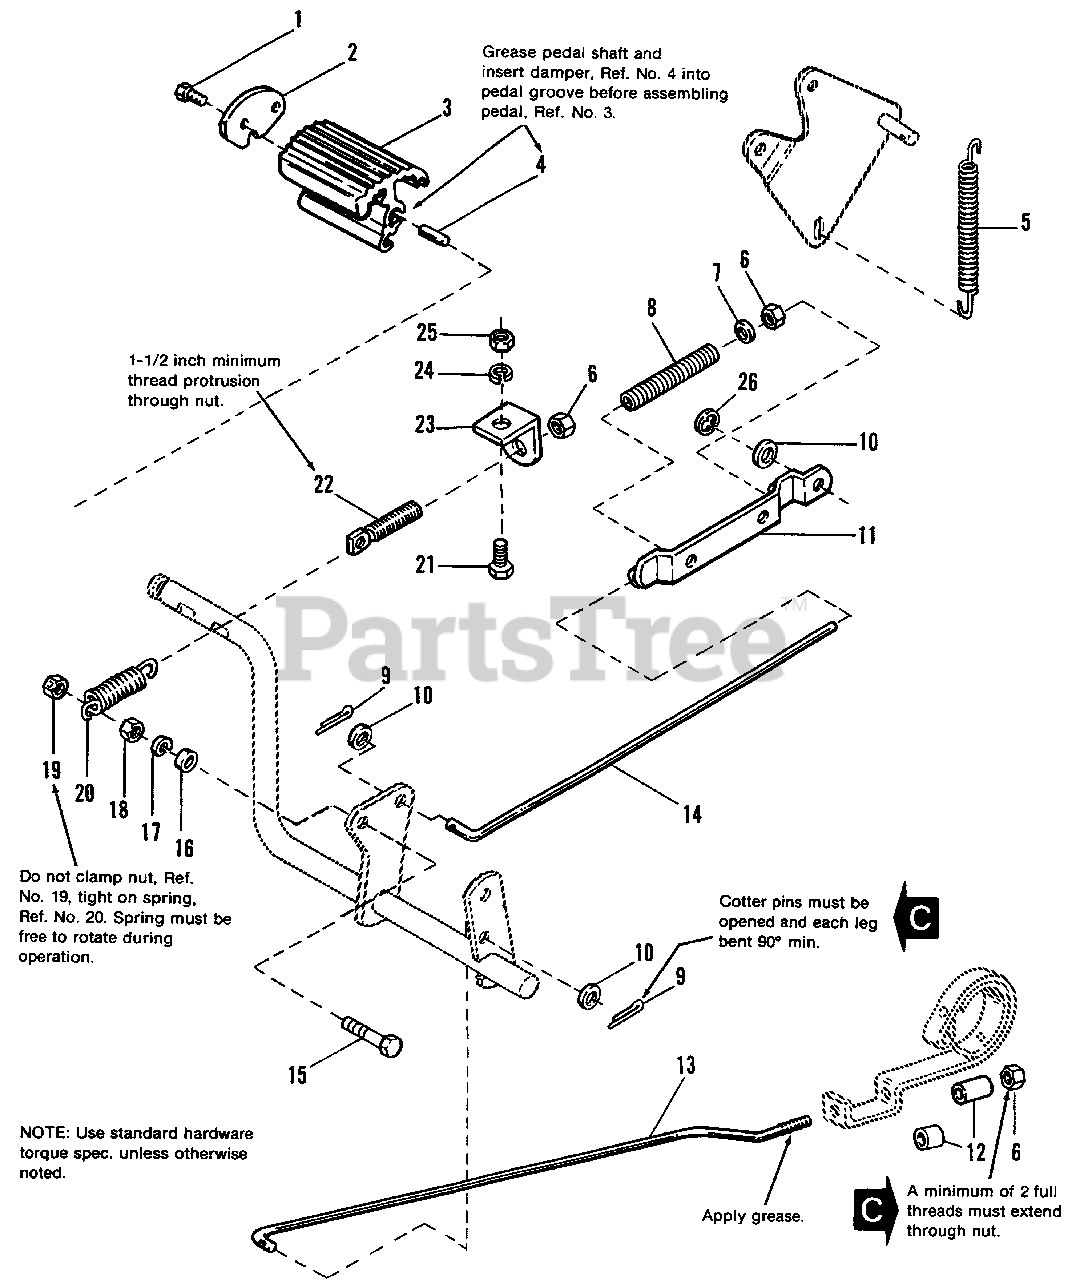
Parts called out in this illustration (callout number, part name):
1	SCREW, Taptite, 1/4-20 x 5/8
2	END PLATE
3	PEDAL, Foot
4	DAMPER, Rubber
5	SPRING, Tension, Idler
6	LOCKNUT, 13/32 I.D. x 1 O.D.
7	WASHER
9	PIN, Cotter, 3/32 x 3/4
10	WASHER, 3/8
11	GUIDE ASSY., Clutch Rod
12	SPACER (Except Mfg. No. 1690927 & 1690930)
12	SPACER (Mfg. No. 1690927 and 1690930)
14	ROD, Clutch (Except Mfg. No. 1690927 and 1690930)
14	ROD, Clutch (Mfg. No. 1690927 and 1690930 only)
15	CAPSCREW, Hex, 3/8-16 x 1-3/4
17	LOCKWASHER, 3/8
18	NUT, Hex, 3/8-16
19	LOCKNUT, Hex, 3/8-16
20	SPRING, Tension
21	CAPSCREW, Hex, 5/16-18 x 1
22	ROD, Tension Adjustment
23	BRACKET, Variator, Spring
24	LOCKWASHER, 5/16
25	NUT, Hex, 5/16-18
